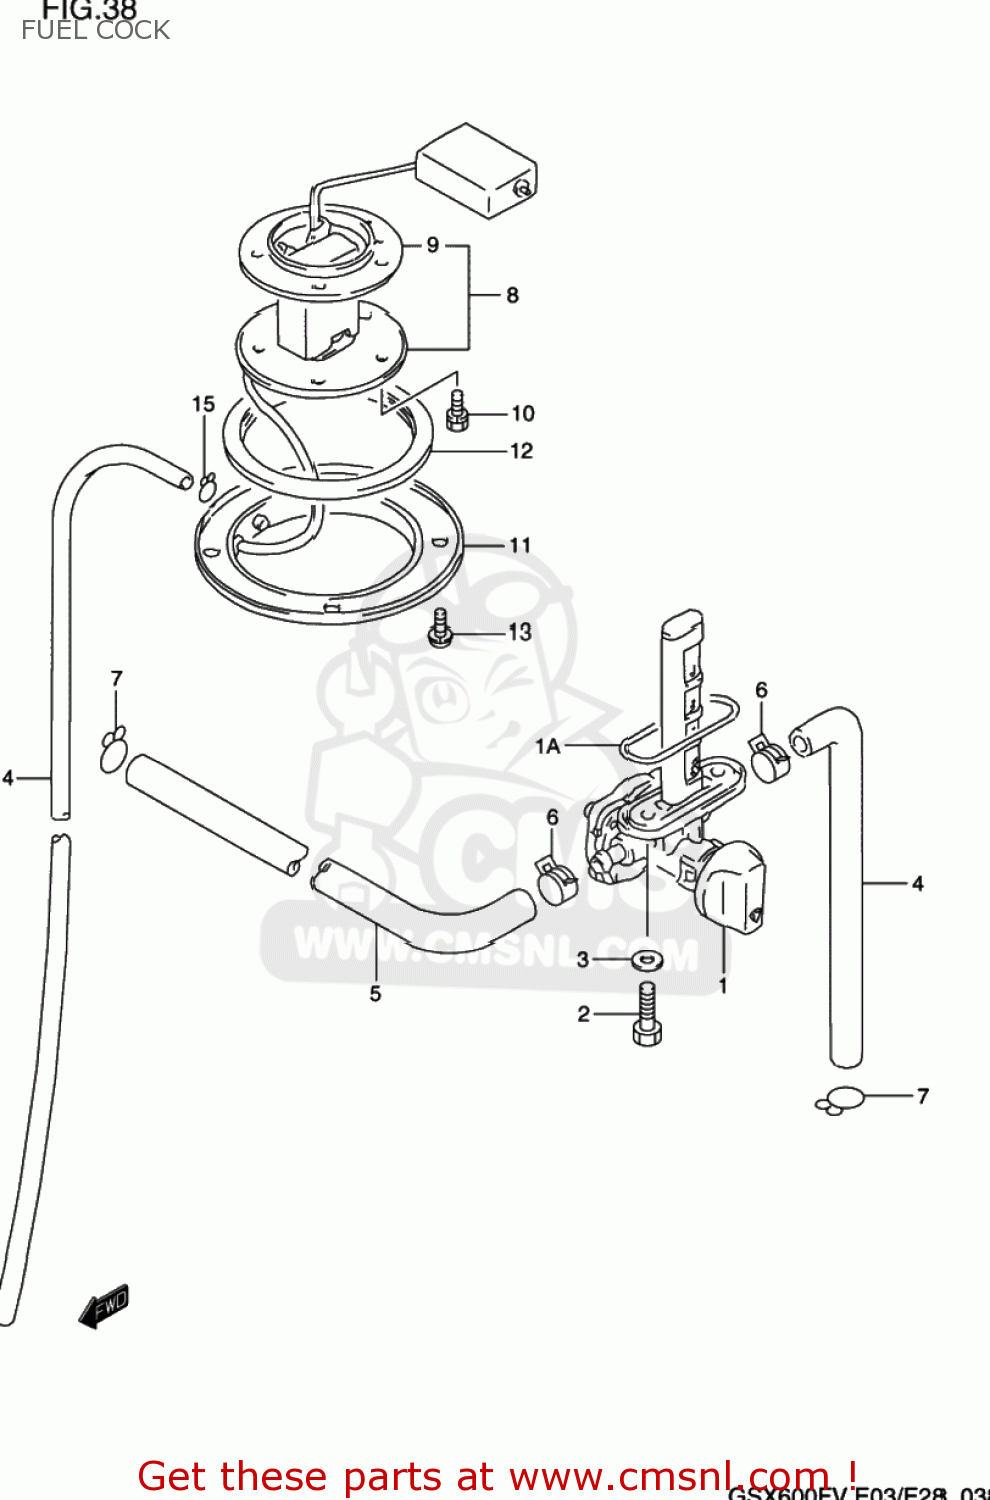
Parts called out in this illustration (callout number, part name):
1	COCK ASSY,FUEL
1A	O RING
2	BOLT(6X20)
3	GASKET(6.4X11.5X0.8) (NAS)
4	HOSE (7X12X150)
5	HOSE (7X12X330)
6	CLIP
7	CLIP
8	GAUGE ASSY,FUEL LEVEL SENDER
9	GASKET,FUEL LEVEL GAUGE (NAS)
10	BOLT 5X10
11	PLATE,FUEL DRAIN
12	GASKET,FUEL DRAIN PLATE (NAS)
13	SCREW(5X8)
14	HOSE(5X8.2X2000)
15	CLIP
